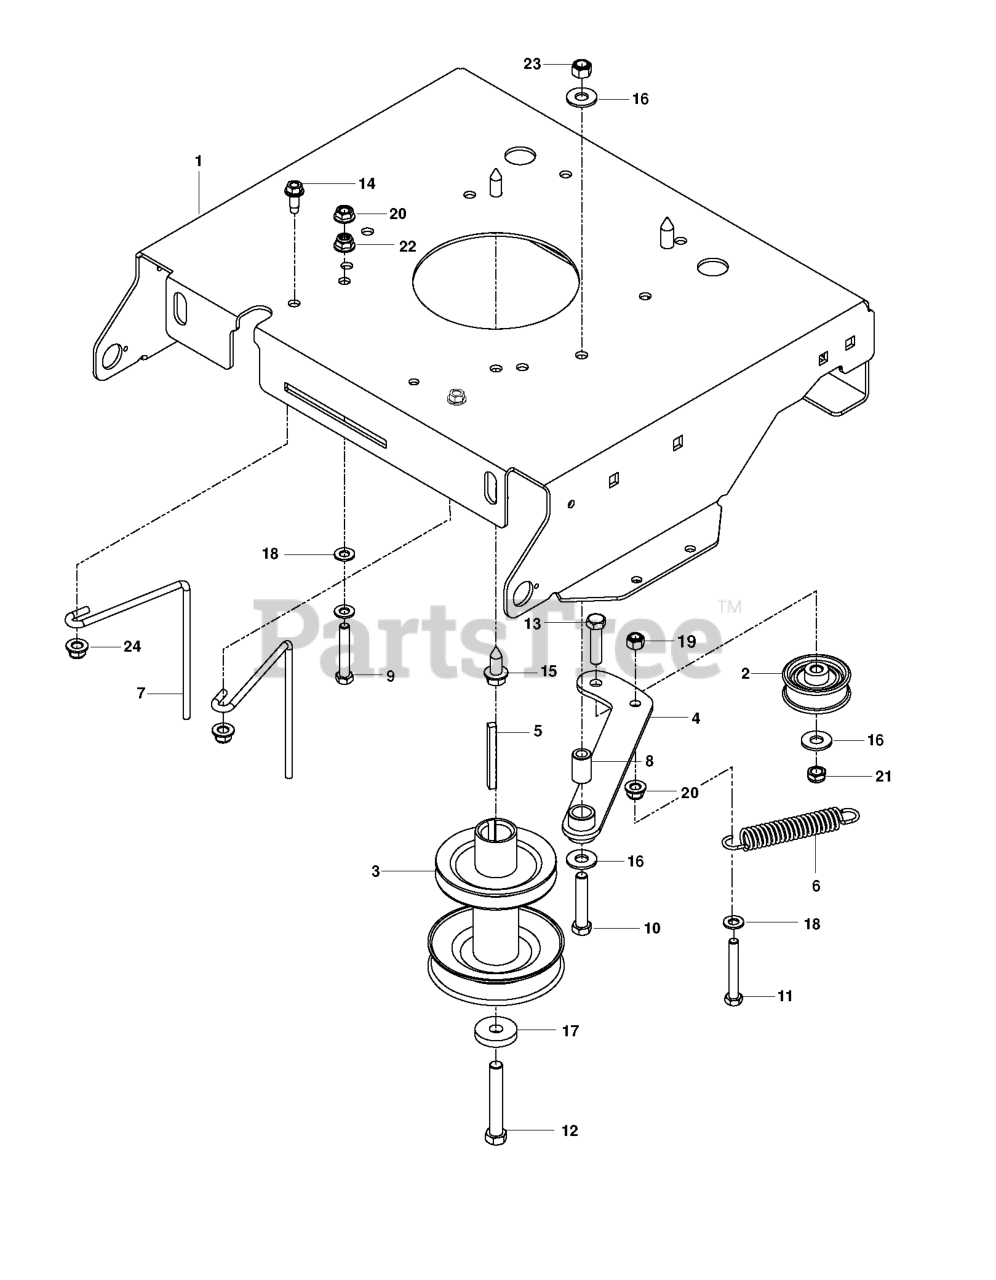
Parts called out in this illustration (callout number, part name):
1	PLATE, ENGINE, ORG
2	PULLEY IDLER
3	PULLEY, ENGINE 30"
4	IDLER WLDT.
5	KEY 1/4 SQ X 2-1/2
6	SPRING - 3.50
7	BELT GUIDE
9	HCS 5/16-18X2
10	HCS 3/8C X 2
12	HCS 7/16-20 X 2-3/4
13	HCS 3/8C X 1 1/2
14	BOLT 3/8-16 X 1.0
15	HHFS 3/8-16 X 1.0 THD FORMING
16	WASHER 3/8 FLAT
17	WASHER .43X1.38X.25
18	FLAT WASHER 5/16 SAE
19	NUT 5/16 NYLOC
20	NUT 5/16C WHIZ
21	NUT HEX 3/8-16 NYLON, THIN
22	5/16-18 NYLOC FLANGE NUT
23	NUT 3/8-16 NYLOC
24	NUT 3/8-16 HEX FLG NYLOC ZD
